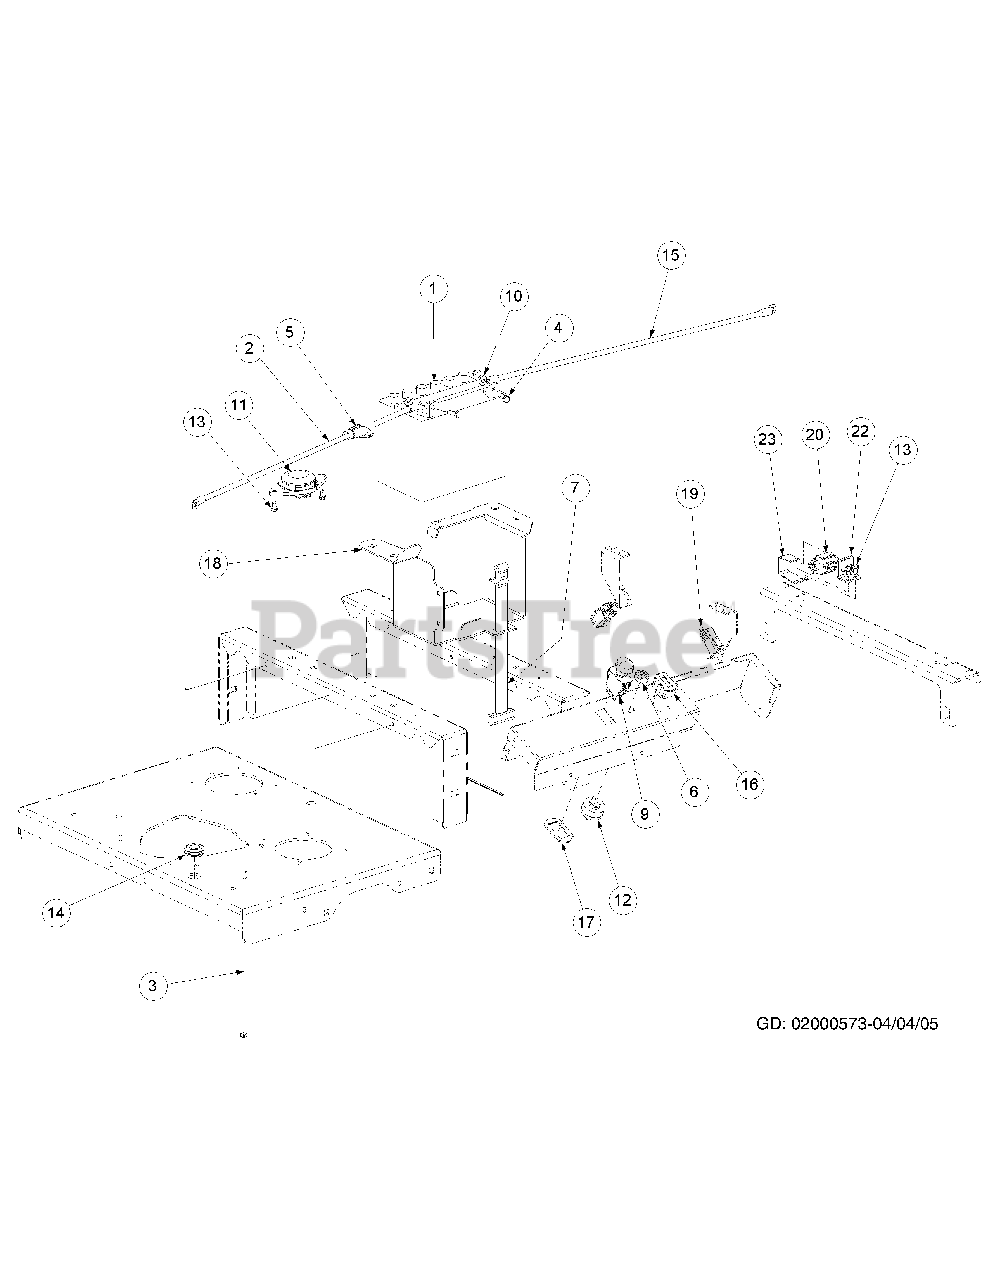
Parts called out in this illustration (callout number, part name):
1	Battery
2	Cable, Battery, Red, 36"
3	Tie, Cable, 3/16 x .05 x 7.4"
4	Screw, Hex, Cap, 1/4-20 x .75
5	Boot, 1" OD Rubber Battery-PST, Red
6	Nut, W/Cap, 5/8-32 Ignition
7	Strap, Battery
9	Switch, Electric, PTO
10	Nut, 1/4-20, Hex Flange Lock Nut
11	Switch, Seat N/C
12	Switch, Ignition, 6 Pin
13	Screw, TT, 1/4-20 x .5, Hex Index Washer
14	Grommet, .75 ID
15	Cable, Battery Black, 28"
16	Meter, Hour
17	Bracket, PTO Switch Retainer
18	Mount Bracket, Battery
19	Switch, Safety
20	Switch, Plunger
22	Switch Bracket Mount
23	Switch Clamp
